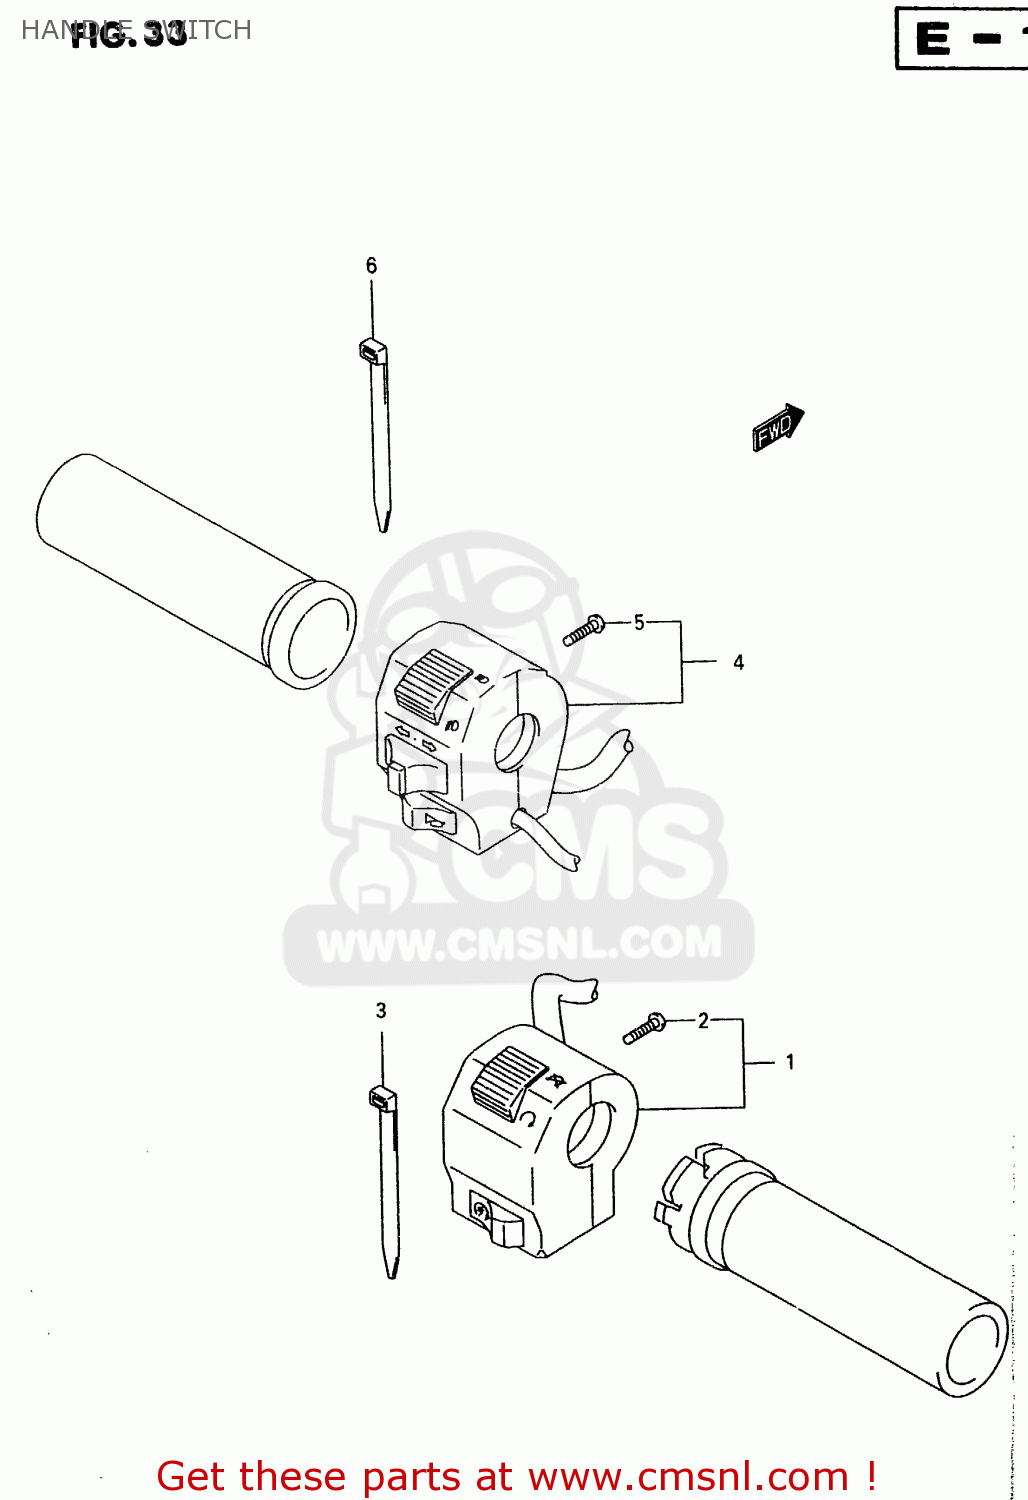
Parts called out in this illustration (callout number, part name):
1	SWITCH ASSY,HANDLE,R
2	SCREW
3	CLAMP(L:145)
4	SWITCH ASSY,HANDLE,L
5	SCREW
6	CLAMP(L:145)
